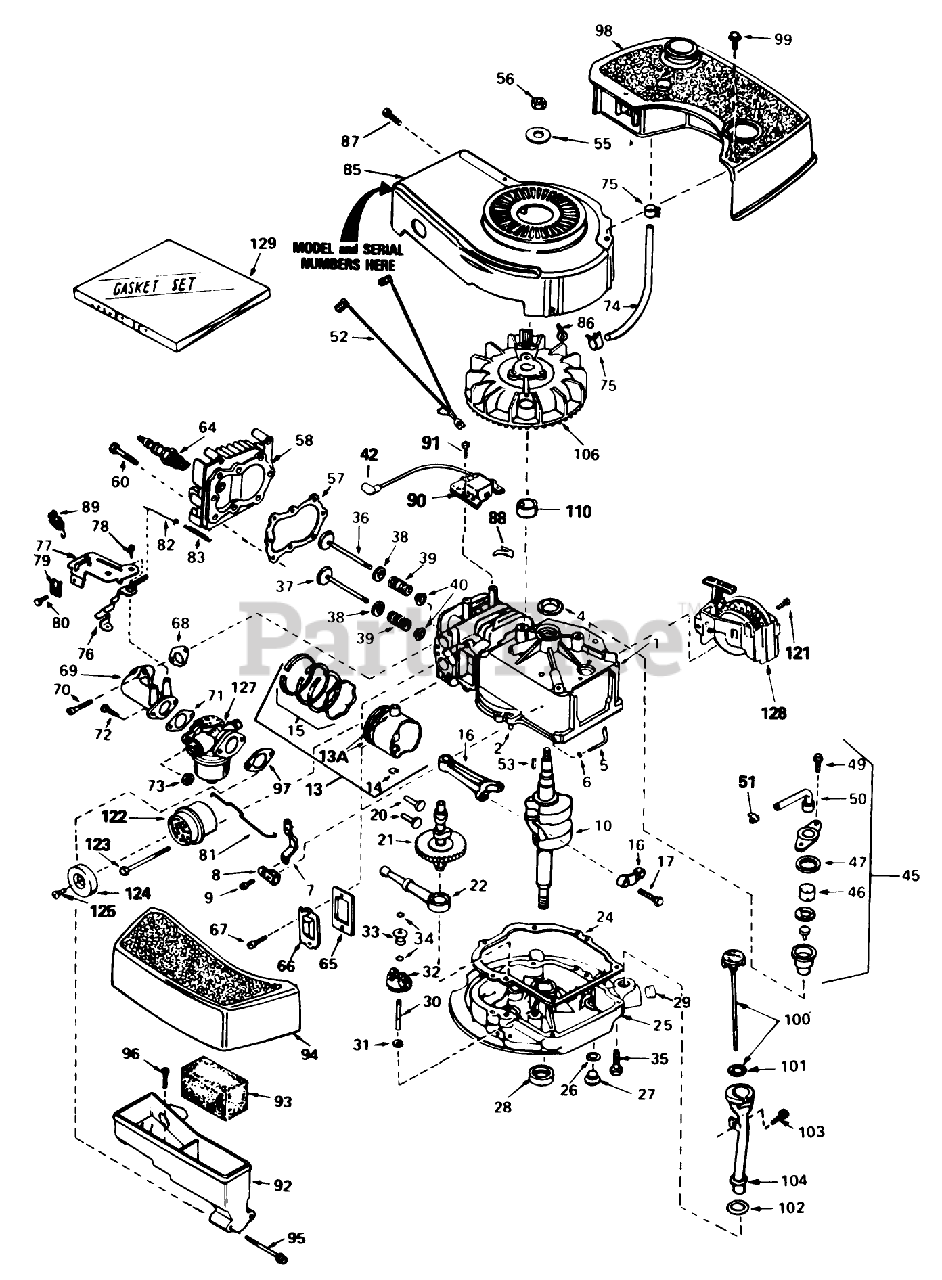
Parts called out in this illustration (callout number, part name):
1	Cylinder Assy. (Incl. #24)
2	Pin-Dowel
4	Seal-Oil
5	Rod, Governor (Incl. No. 36)
6	Washer-Flat
7	Governor Lever
8	Clamp-Lever, Governor
9	Screw
10	Crankshaft
13	Piston, Pin Ring Assy. (Std.) (Incl. Ref. #13A, 14 15)
13	Piston, Pin Ring Assy. (.010 oversize) (Incl. Ref. #13A, 14 15)
13	Piston, Pin Ring Assy. (.020 oversize) (Incl. Ref. #13A, 14 15)
13A	Piston Pin Assy. (Incl . Ref. . #14) (Std.)
13A	Piston Pin Assy. (Incl. Ref. #14) (.010 Oversize)
13A	Piston Pin Assy. (.020 oversize) (Incl. Ref. #14)
14	Ring-Retaining, Piston Pin
15	Ring Set (Std.)
15	Ring Set (.020" OS)
15	Ring Set (.010" OS)
16	Rod Assy., Connecting (Incl. Ref. #17)
17	Bolt-Rod, Connecting
20	Lifter-Valve
21	Camshaft(Mech.Comp. Release)
22	Oil Pump ASM
24	Gasket, Mounting
25	Flange Assy., Mounting (Incl. Ref. #26thru 30)
26	Gasket-Oil Drain
27	Plug Oil Drain
28	Seal Oil
29	Plug-Pipe
30	Shaft-Governor
31	Washer-Flat
32	Governor Gear ASM
33	Spool-Governor
34	Ring-Retaining
35	Screw (1/4-20 x 1-1/4)
36	Valve, Intake (Std.) (Incl. Ref. #40)
36	Valve, Intake (1/32" oversize)(Incl. No. 40)
37	Valve, Exhaust (Std.)(Incl. No. 40)
37	Valve, Intake (1/32" oversize)(Incl. No. 40)
38	Cap-Upper Valve Spring
39	Spring-Valve
40	Cap-Valve, Spring
42	Cover-Spark Plug
45	Breather Assy. (Incl. Ref. #46 thru 51)
46	Element-Breather
47	Gasket-Breather
49	Screw (10-24 x 9/16)
50	Tube, Breaker
51	Clip, Breather
52	Wire-Ground
53	Key-Flywheel
55	Washer-Belleville
56	Nut-Flywheel
57	63573 GIL 42 SNWTHW
58	Head-Cylinder
60	Screw (5/16-18x1-1/2)
64	Plug, Spark (J17LM or equiv.)
64	Plug, Spark (Champion RCJ-8)
65	Gasket-Breather
66	Cover-Valve
67	Screw
68	Gasket-Intake
69	Pipe, Intake (Incl. No. 68)
70	Screw (1/4-20 x 1)
71	Gasket-Carburetor
73	Nut and Lock Washer (1/4-28)
74	Line-Fuel
75	Clamp-Line, Fuel
76	Lever Control
77	Control Assy., Speed (Incl. Nos, 76, 78 89)
78	Screw, Hex Washer Hd Shoulder Self-Tap
79	Conduit
80	Screw (10-32 x 3/8)
81	Link-Throttle
82	Link Governor Spring
83	Spring Governor
85	Housing-Blower
86	Screw (1/4-20x19/32)
87	Screw (10-24 x 9/16)
88	Clip, Spring
89	Terminal
90	Solid State
91	Screw
92	Body Air Cleaner
93	Filer, Air
94	Cove, Air Cleaner
95	Screw Fil Hd.
96	Screw, Hex Hd.
97	Gasket-Air Cleaner
98	Tank-Fuel
99	Screw (10-32 x 35/64)
100	Dipstick, Oil (Incl. Ref. #101)(Twist Lock)
101	O-Ring
102	Gasket
103	Screw (10-32 x 1/2)
104	Tube-Oil Fill
106	Flywheel
110	Spacer
121	Screw (1/2-20x5/8)
122	Muffler (Incl. Ref. #122)
123	Screw
124	Cover-Muffler
125	Screw
127	Carburetor (Incl. Ref. #71)
128	Starter-Sidemount
129	Gasket Set
